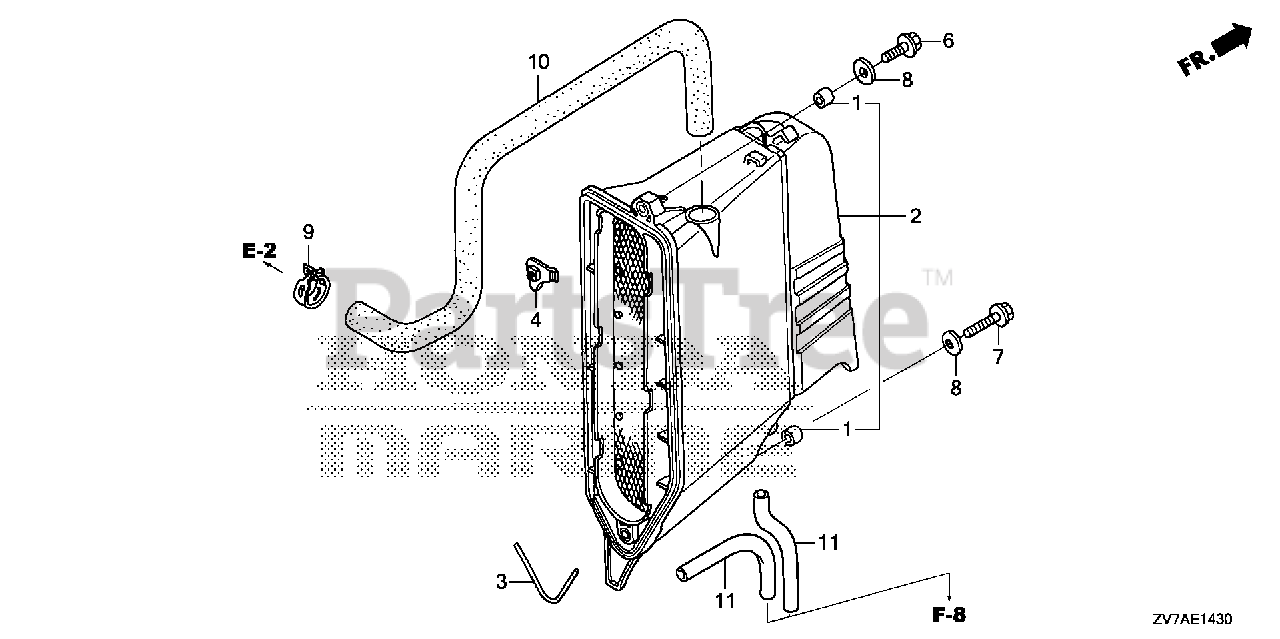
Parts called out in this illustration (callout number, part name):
1	COLLAR, DISTANCE
2	COVER, MUFFLER
3	GASKET, MUFFLER COVER
4	NUT, MUFFLER COVER
6	BOLT, FLANGE (6X25)
7	BOLT, FLANGE (6X40)
8	WASHER (6.5X18)
9	CLAMP, TUBE (D17)
10	TUBE, BREATHER
11	BULK HOSE, VINYL (4.5X8X1000) (4.5X8X70)
